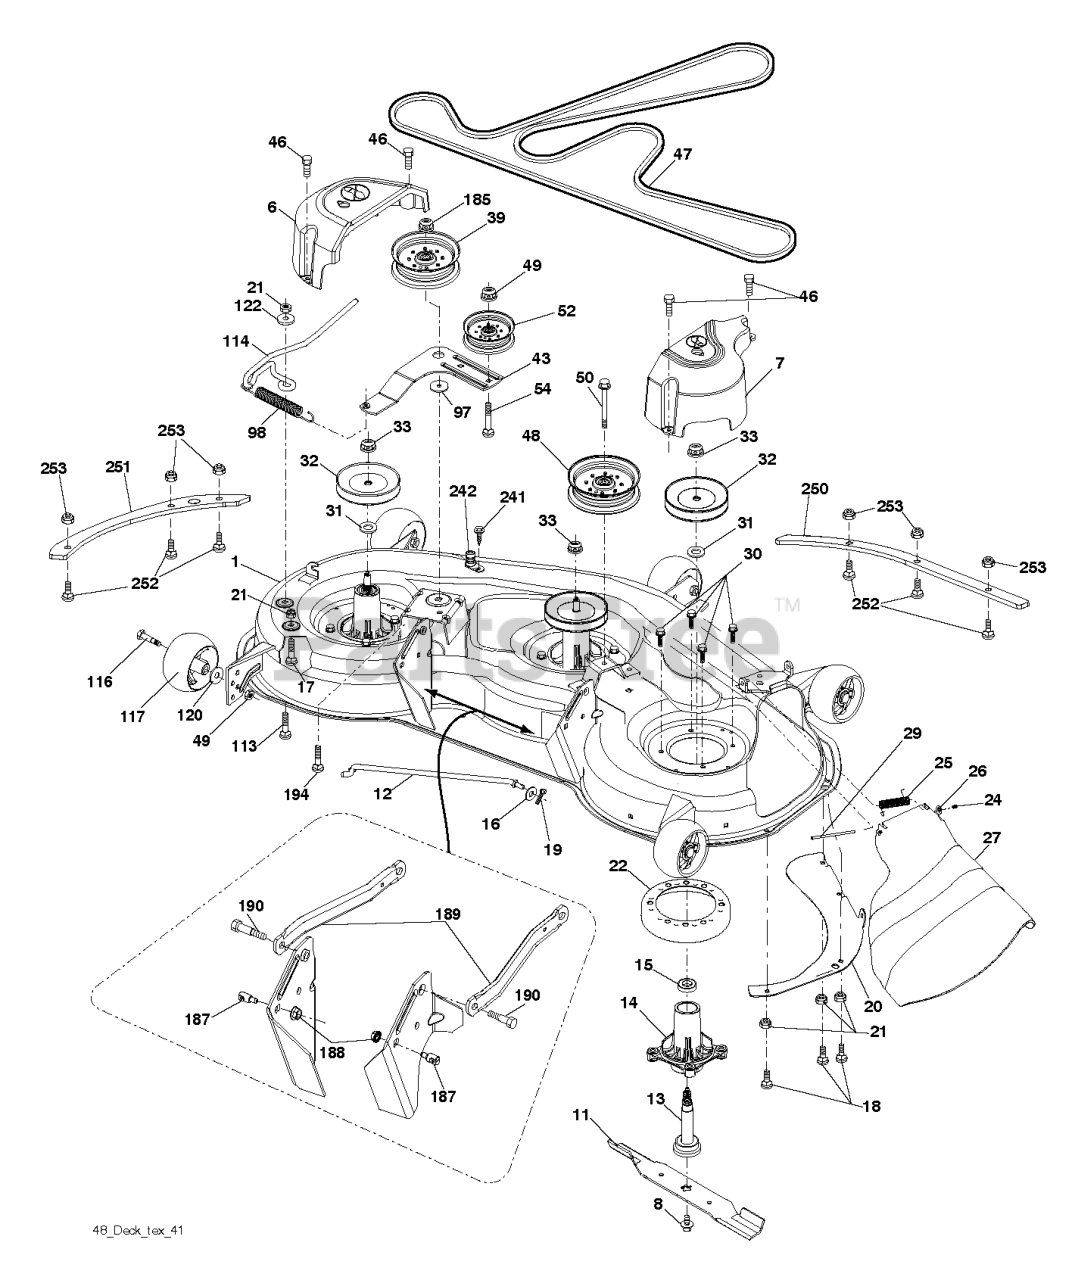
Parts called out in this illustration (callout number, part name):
1	DECK.WLDMT.W/TUBES.48".OR.RP
6	COVER.MANDREL.LH.48"(2 2)
7	COVER.MANDREL.RH.48"
8	BOLT.WASHER.ASM.7/16-2
11	48" HI-LIFT BLADE
12	ROD.ANTI.SWAY.48/54"K4
13	SHAFT ASM MANDREL
14	RP.HOUSING.MANDREL.4PT.
16	WASHER
17	BOLT.CARR.5/16-18X5/8.SHORT
18	BOLT
19	PIN.COTTER.5/16.BOW TI
20	BAFFLE, VORTEX MWR
21	LOCKNUT
22	STRIPPER.MANDREL.ROUND.BLACK
24	CAP-SLEEVE LT
25	SPRING, TORSION
26	NUT PUSH M
27	DEFLECTOR SUBS TO 532 180655
29	ROD.HINGE
30	SCREW, WASHER HEAD
31	WASHER.SPACER.MANDREL
32	PULLEY MANDREL
33	NUT.FLANGE.LOCK.TOP
39	RB PULLEY.IDLER.4.50/HUB SPEC
43	ARM.IDLER
46	SCREW.1/4-20X5/8
47	BELT.DRIVE.DECK
48	PULLEY.IDLER.2006
49	NUT LOCK FLG 3/8-16 UNC
50	SCREW TT 3/8-16X2-1/4 UNC
52	PULLEY.IDLER.48"PRIMARY
54	BOLT.3/8-16X1.50
98	SPRING, DECK DRIVE
113	BOLT CRT
114	ROD.TENSION.RELIEF.TEX (2 2)
116	BOLT.SHOULDER.3/8-16X3-5/8.
117	RP WHEEL. GUAGE RALLY
120	WASHER
122	BUSHING.RELIEF.TENSION
185	NUT.LOCK.FLANGE.7/16
187	STUD.FASTNER.W/ANTI-ROTATE
188	NUT LOCK HEX FLANGE 5/16-18
189	ARM.SUSPENSION.MOWER
190	BOLT.SHOULDER
194	BOLT.HEX.WASHER.HEAD.7/16-24X
241	SCREW.TT.#10-32X.5.3/8.FLANGE
242	PORT.WASHOUT
250	PLATE.REIN.FRNT.BOLTON.48X431
251	PLATE.REIN.SIDE.BOLT.ON.48X431
252	RHSNB, 1/4-20 X 1, GR5
253	NUT T
